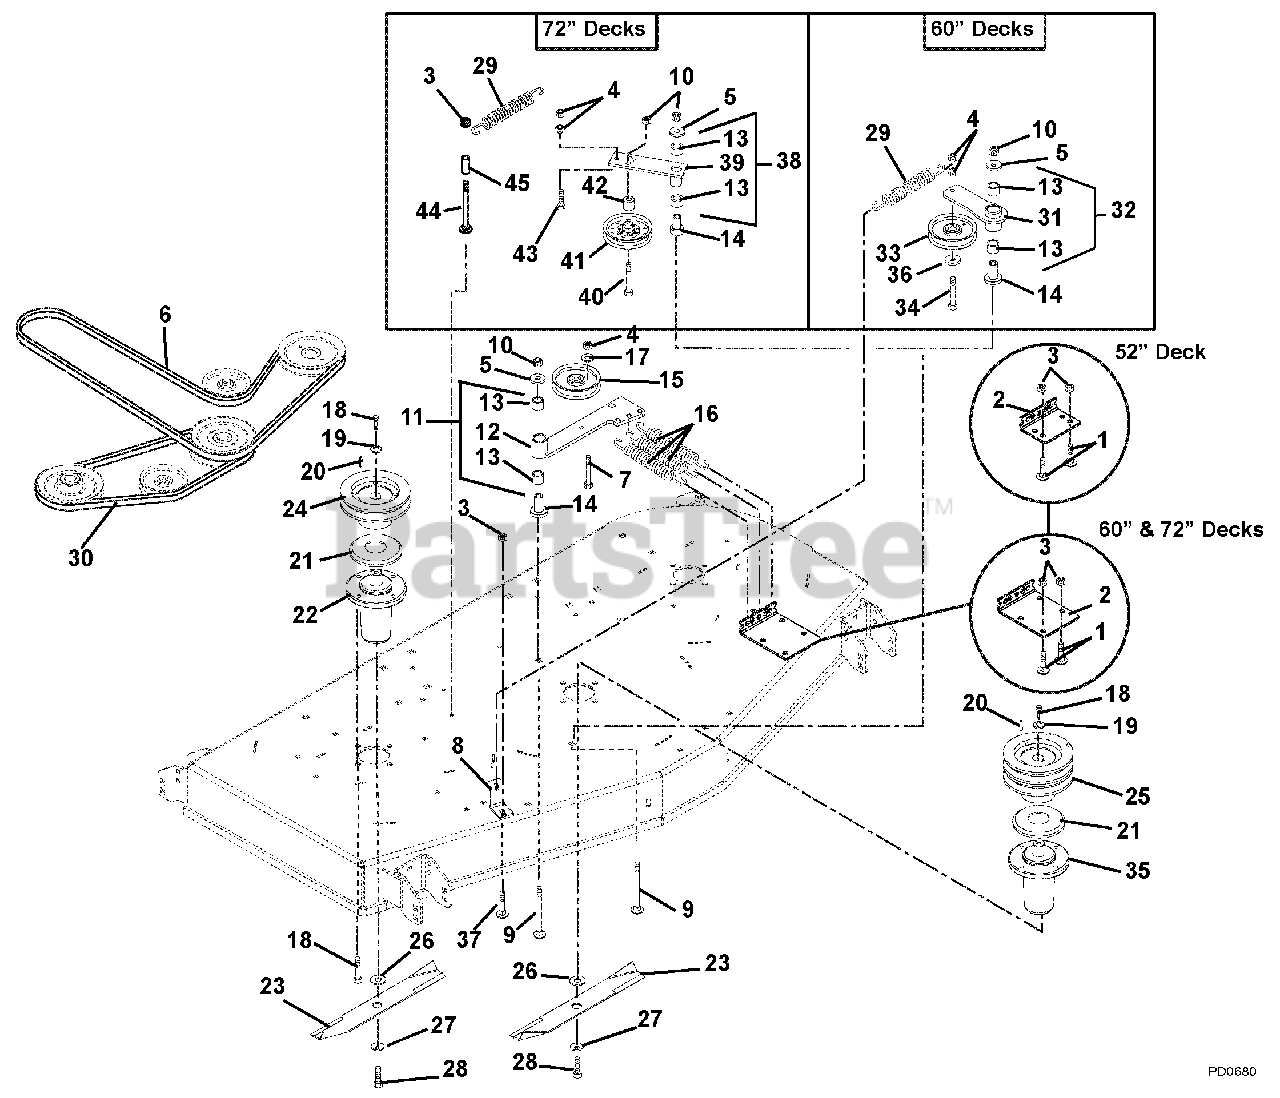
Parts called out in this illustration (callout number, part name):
1	@BLT-RDHDSQNK .38-16X.75 G5YZ
2	BRACKET,LONG SPRING (DIESEL)
2	BRACKET, SHORT SPRING (GAS)
3	@NUT-LK-TOP-FLG .38-16 YWZC
4	@NUT-LK-CTR .38-16 YWZC
5	@WSHR-FL-STL.50X1.25X.083 YWZC
6	V-BELT, HB-WRAPPED
7	@BLT-RDHDSQNK .38-16X2.75 G5YZ
8	ANCHOR, SPRING (RED)
9	@BLT-RHDSSQNK .50-13X3.50 G5YZ
10	@NUT-LK-TOP-FLG .50-13 YWZC
11	ASSY-DECK IDLER PIVOT ARM
12	WMT, DECK IDLER PIVOT ARM
13	BRG, 1.00 X 1.12 X .75
14	BEARING, PEDESTAL
15	IDLER-FLAT 4.00 X .38 (2.32W)
16	SPRING,EXT TO 08300513
17	WSHR-FL-STL .375X1.125X.065YWZ
18	BLT-HEX .38-16X1.0 GR8 YZ EP30
19	WSHR,FLT STL.406X1.50X.245YWZC
20	KEY, SQ .25X.25X1.00 RC 40-50
21	SLINGER, DUST
22	ASM,MAINT FREE SPINDLE
23	BLADE, MULCHING (20.50")
23	BLADE, MULCH 18.00"
23	BLADE,MOWER-72"MULCH(24.5"LG)
24	WELDMENT, SPINDLE SHEAVE 6.00
25	SHEAVE, DOUBLE (6.25")
26	WSHR-FLT .640X1.75X.250 YWZC
27	WSHR-BLVL .669X1.535X.138
28	BLT-HEX .62-18X1.75 GR8 YWZC
29	SPRING, EXT
30	V-BELT, HB-RAW EDGE
31	WMT, IDLER PIVOT ARM
32	ASM, IDLER PIVOT ARM
33	V-IDLER, 4.00X.38
34	@BLT-HEX .38-16X2.25 GR5 YWZC
35	ASM,MAINT FREE SPINDLE
36	@WSHR-FL-STL.406X.812X.065 YWZ
37	@BLT-RDHDSQNK .38-16X1.00 G5YZ
38	ASSEMBLY,IDLER ARM GRD.DRIVE
39	WMT, IDLER ARM GROUND DRIVE
40	@BLT-HEX .50-13X2.50 GR5 YWZC
41	IDLER-FLAT-PLY 6.75X.510
42	SPACER .513X.748X.620
43	@BLT-HEX .38-16X1.25 GR5 YWZC
44	@BLT-RDHDSQNK .38-16X2.75 G5YZ
45	SPACER .380 X .625 X 1.500
